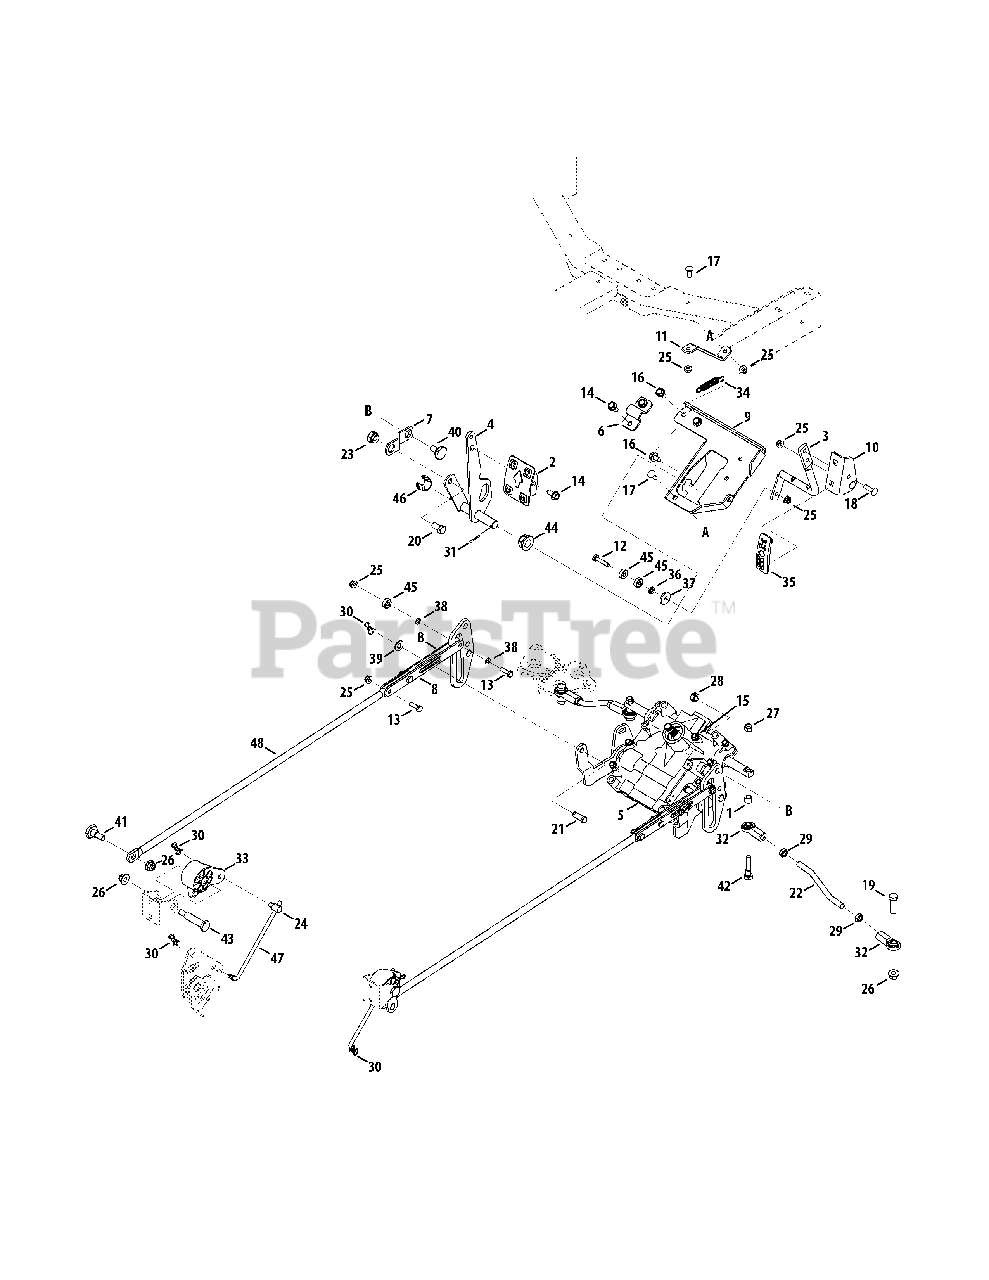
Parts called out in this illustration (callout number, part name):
1	Spacer, 344 x .500 x .375
2	Forward Pedal Assembly
3	Reverse Pedal Rod
4	Forward Bracket Assembly
5	Steering Assembly
6	Reverse Bearing Bracket
7	Control Bracket
8	Steering Link Plate
9	Pedal Mount Bracket
10	Reverse Pedal Bracket
11	Pedal Mount Plate Support Bracket
12	Hex Head Screw, 1/4-20 x 1.25
13	Hex Screw, 1/4-20 x .875
14	Hex Washer Screw, 5/16-18 x .750
15	Hex Washer Screw, 1/4-20 x .500
16	Hex Washer Screw, 5/16-18 x .625
17	Carriage Screw, 1/4-20 x .75
18	Carriage Screw, 1/4-20 x 1.00
19	Hex Screw, 3/8-16 x 1.25
20	Hex Screw, 3/8-16 x .750
21	Clevis Pin, .375 x .969
22	Rod, 3/8 x 5.0
23	Neutral Adjustment Hub
24	Adjustment Ferrule, 1/4-28 x 1.000
25	Flange Lock Nut, 1/4-20
26	Flange Lock Nut, 3/8-16
27	Hex Lock Nut, 5/16-24
28	Hex Lock Nut, 3/8-16
29	Jam Nut, 3/8-24
30	Bow-Tie Cotter Pin, 72
31	Cotter Pin, 3/32 x .750
32	Female Ball-Joint
33	Pivot Arm, LH
33	Pivot Arm, RH
34	Extension Spring, .429 x 2.515
35	Reverse Foot Pad
36	Flat Washer, .281 x .500 x .063
37	Flat Washer, .265 x .938 x .120
38	Flat Washer, .281 x .50 x .04
39	Thrust Washer, .375 x .812 x .060
40	Shoulder Screw, .625 x .217
41	Shoulder Screw, .500 x .434
42	Shoulder Screw, 375 x .48
43	Shoulder Screw, .500 x 1.825
44	Hex Flange Bearing
45	Ball Bearing, .25 x .6875 x .25
46	Hex Flange Bearing, .628
47	Hydro Control Rod
48	Hydro Link Rod
